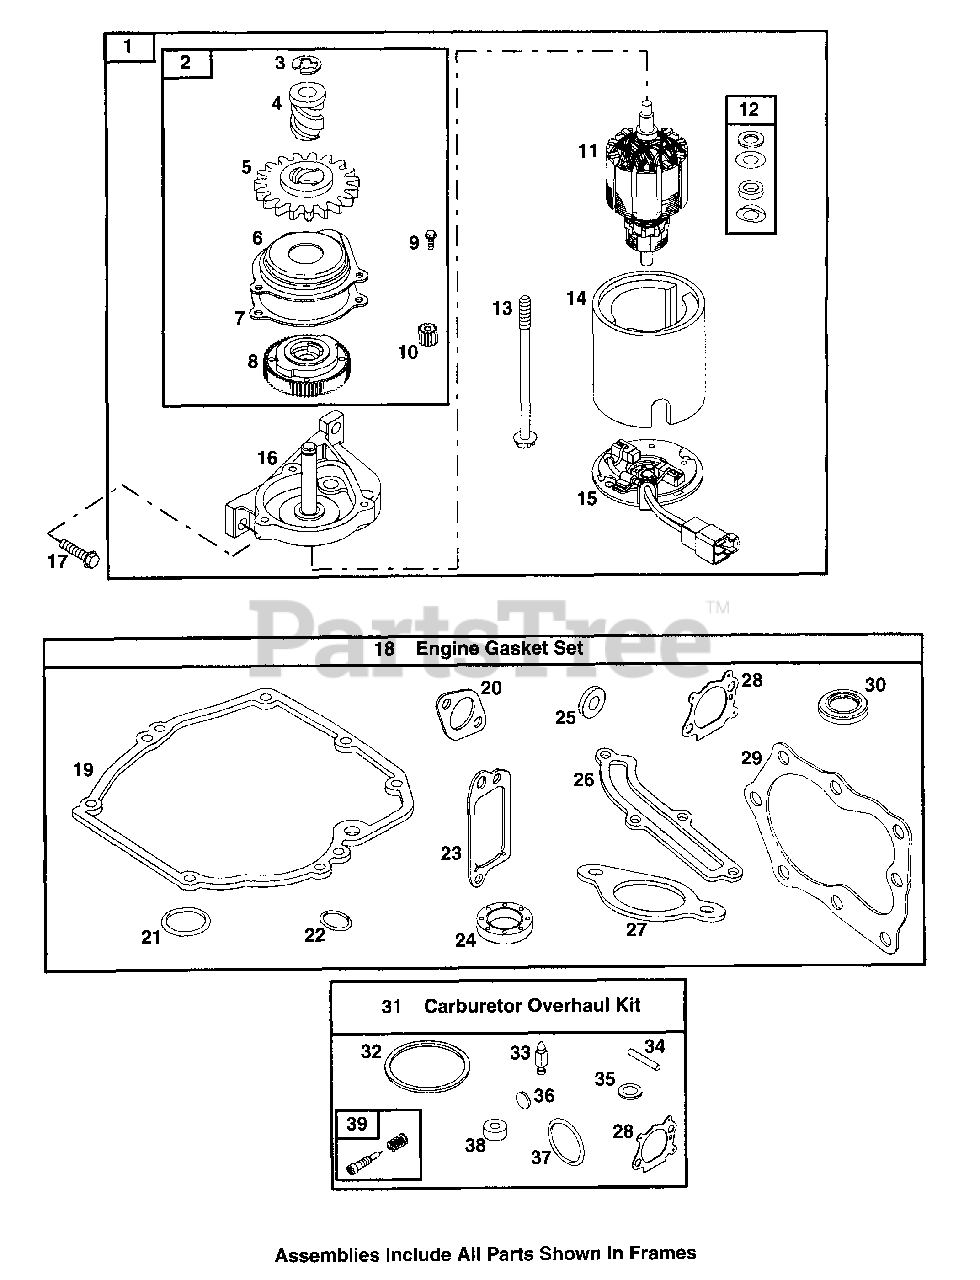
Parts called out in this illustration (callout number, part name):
1	Starter Motor
2	Starter Drive
3	E-Ring Retainer
4	Starter Spline
5	Pinion Gear
6	Starter Gear Cover
7	Starter Cover Gasket
8	Drive Clutch
9	Screw (Starter Drive Cover)
10	Pinion Gear
11	Starter Armature
12	Washer Set
13	Bolt (Starter Motor)
14	Starter Housing
17	Screw (Drive Cap)
18	Engine Gasket Set
19	Crankcase Gasket
20	Exhaust Gasket
21	Dipstick/Tube Seal
22	Dipstick Tube Seal
23	Breather Gasket
24	Oil Seal (PTO Side)
25	Spacer
26	Breather Passage Gasket
27	Intake Gasket
28	Air Cleaner Gasket
29	Cylinder Head Gasket
30	Bushing/Seal Kit
31	Carburetor Overhaul Kit
32	Float Bowl Gasket
33	Needle/Seat Kit
34	Float Hinge Pin
35	Sealing Washer
36	Welch Plug
37	O-Ring Seal (Intake Manifold)
38	Choke/Throttle Dust Seal
39	Idle Mixture Kit
